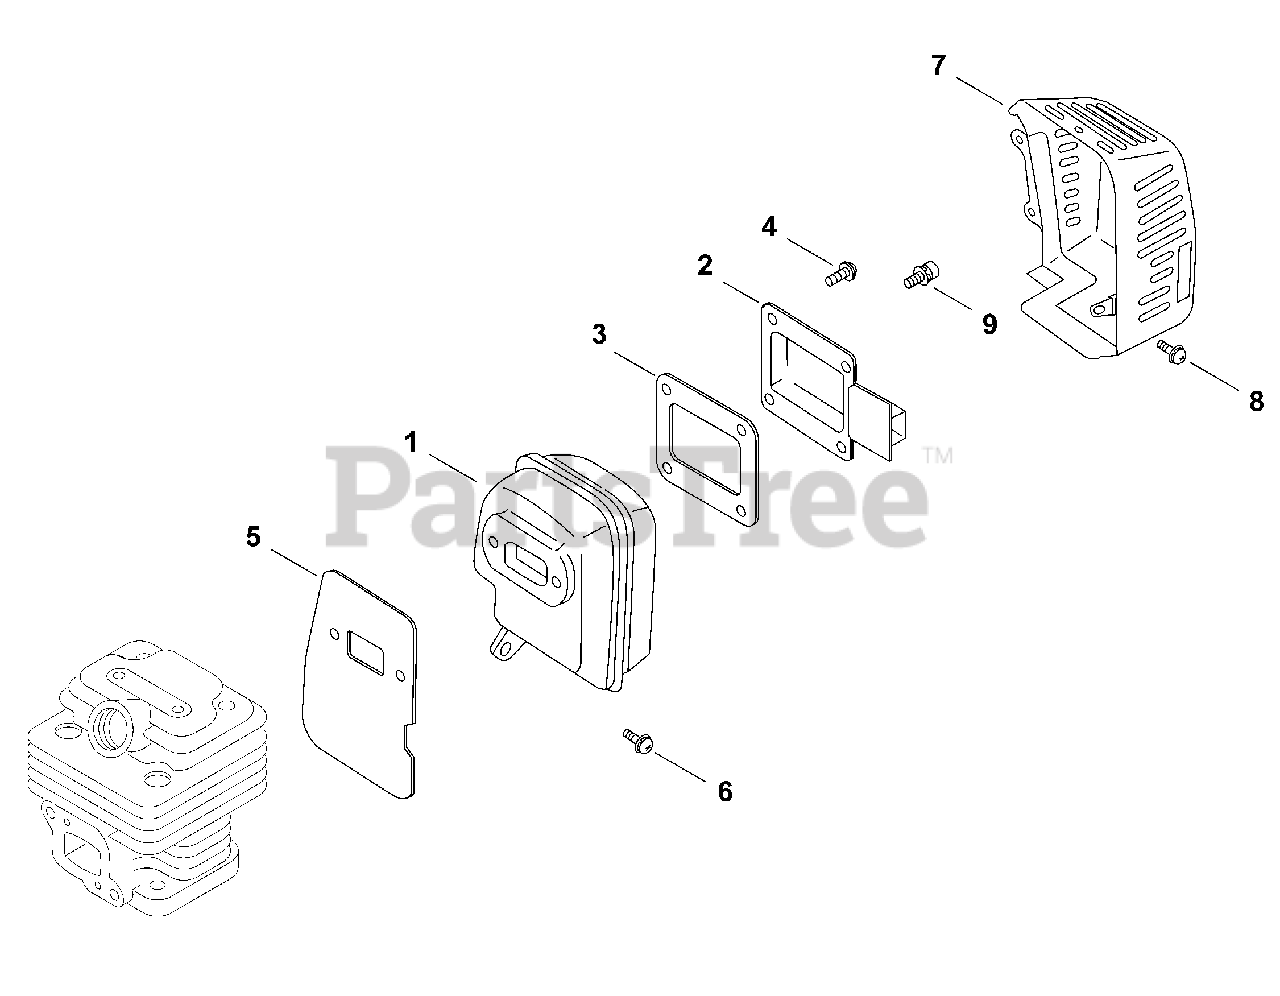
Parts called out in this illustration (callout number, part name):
2	GUIDE, EXHAUST
3	GASKET, EXHAUST
4	SCREW 4×10
5	GASKET, MUFFLER
6	SCREW 5×14
7	COVER, MUFFLER
8	SCREW 4×10
9	BOLT 5×20
